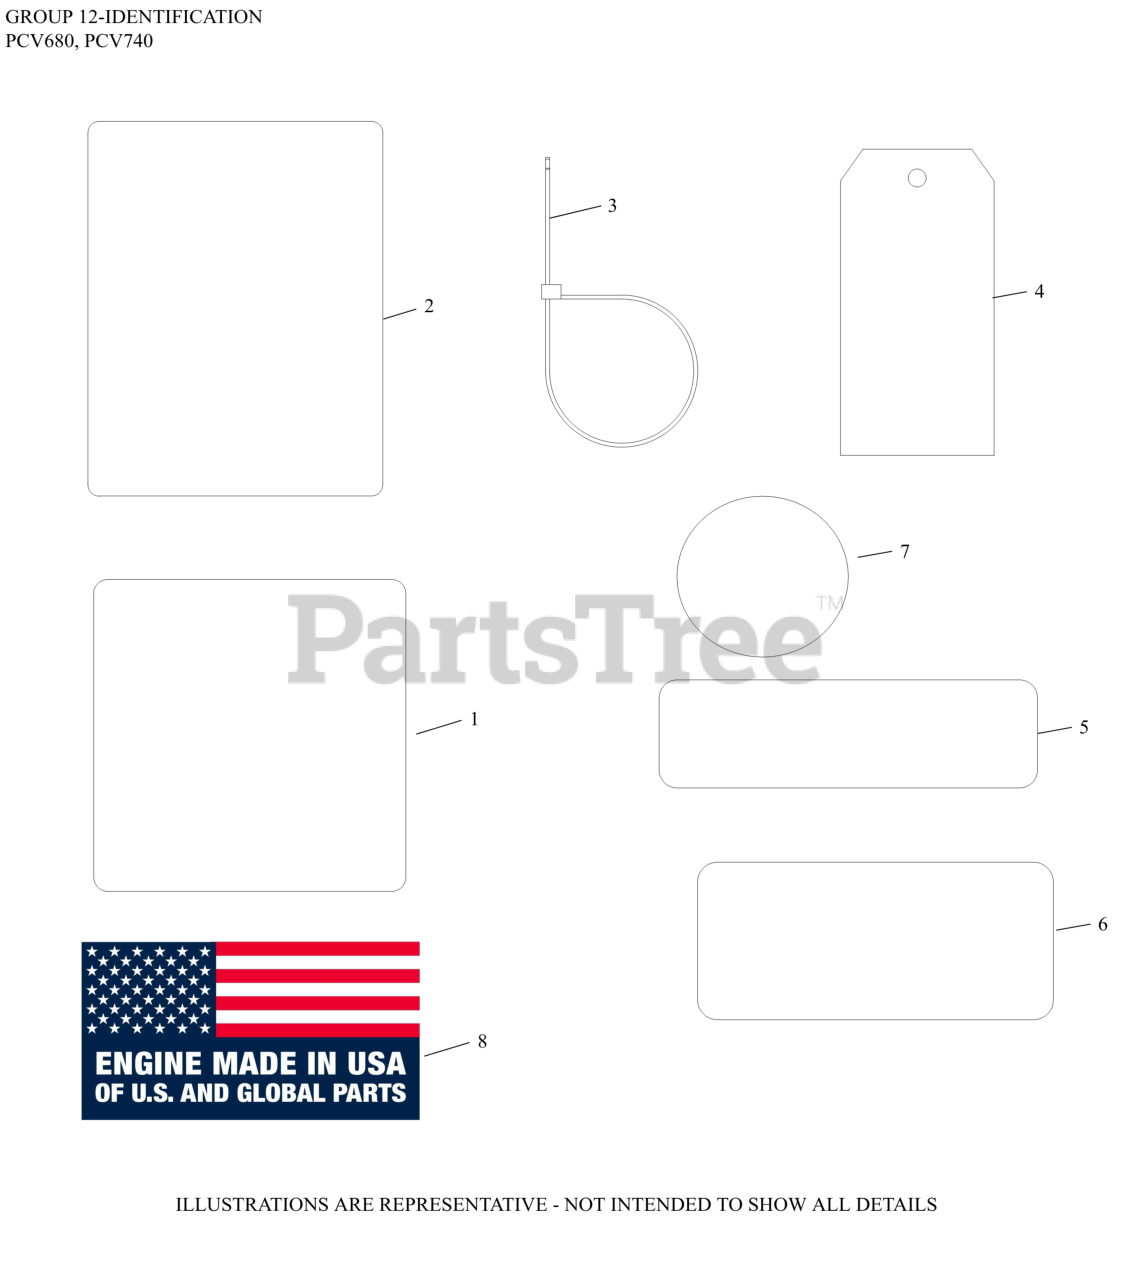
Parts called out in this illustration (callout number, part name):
1	DECAL HDAC, 747cc/PCV-PCH740
2	LABEL, CLEAR LAMINATION
6	DECAL, SYNTHETIC OIL
8	DECAL, USA
